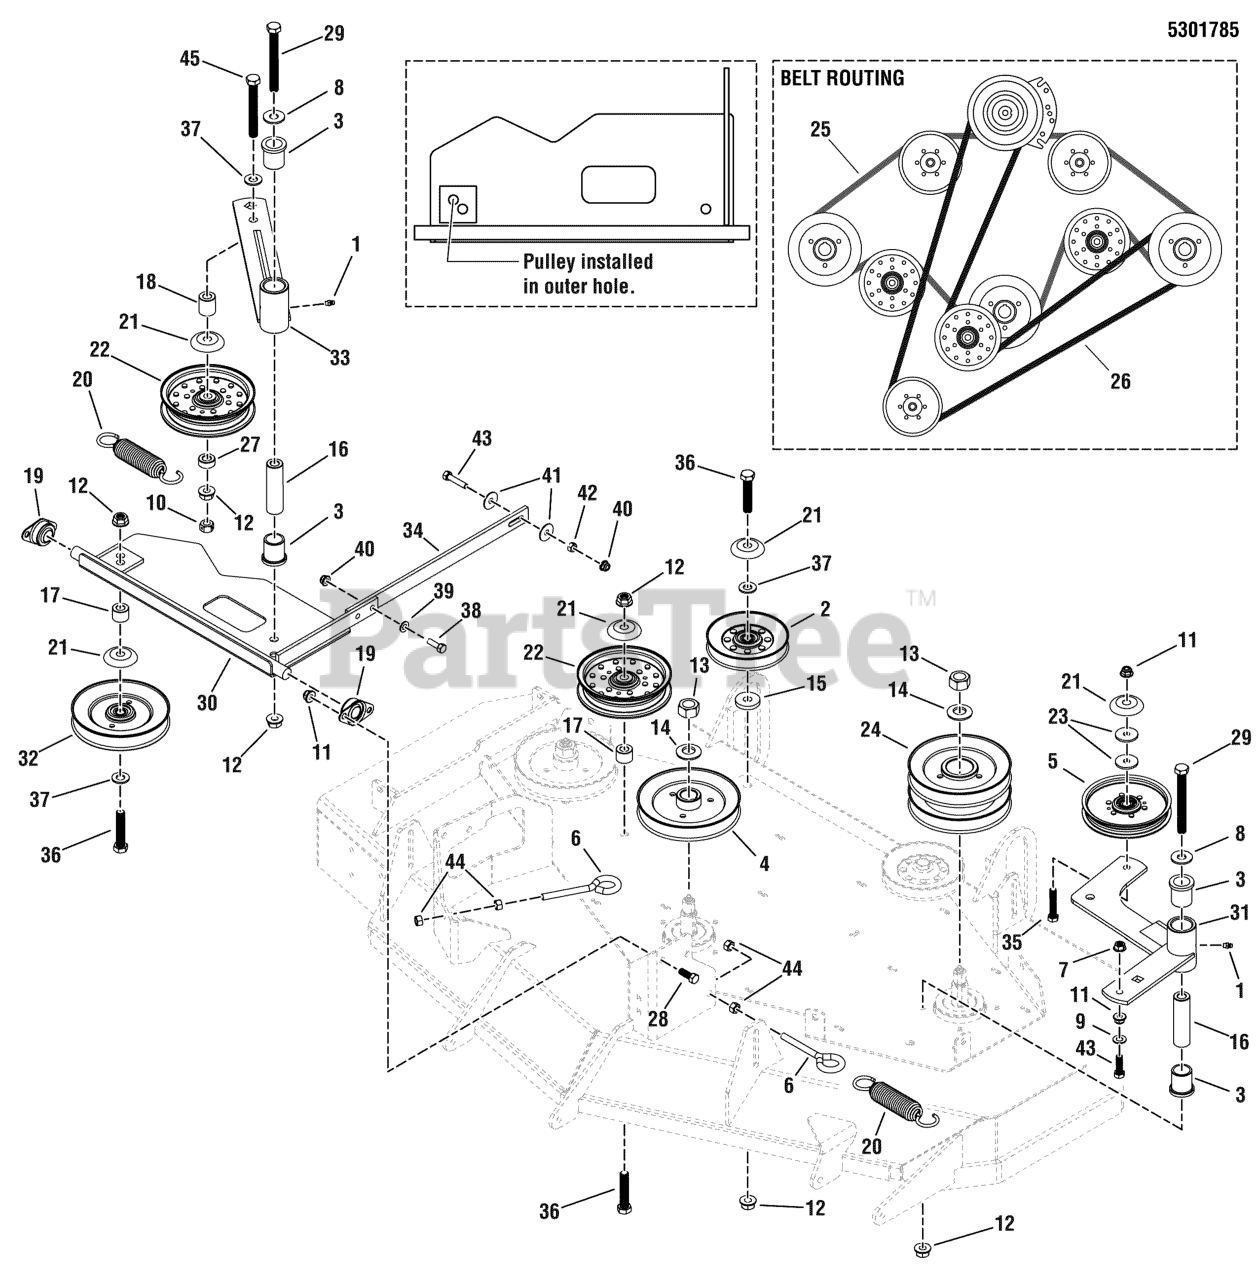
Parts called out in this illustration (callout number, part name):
1	GREASE FITTING, 1/4-28 STRAIGHT
2	PULLEY-IDLER-V, 4.85OB, .506ID, .94W,STL
3	BUSHING, FLANGE
4	PULLEY, 5.926 OVER BALL
5	PULLEY-IDLER, 5.00OD, .385ID, .75W, STL
6	EYE BOLT, 3/8-16 X 5, 2.88THRD, 1EYE, CZ
7	NUT, 3/8-16 HEX SERRATED FLANGE
8	WASHER, 1/2 USS
9	WASHER, 3/8 SAE
10	NUT, 1/2-13 HEX SIDE LOCK
11	NUT, 3/8-16 HEX NYLOCK FLANGE
12	NUT, Hex Flange, Nylock, 1/2-13
13	NUT, 3/4-16 HEX
14	WASHER, 3/4 BELLEVILLE
15	WASHER, .53 X 1.50 X .25
16	SPACER, .52 X 1.00 X 3.50
17	SPACER, .52 X 1.00 X .75
18	SPACER, .52 X 1.00 X 1.15
19	BEARING, BRONZE FLANGE, 3/4"
20	SPRING, EXTENSION, SWIVEL, SHORT HOOK
21	SHIELD, PULLEY BEARING
22	PULLEY, IDLER, 5" OD, 1"FACE, 5.75 FL
23	WASHER, .390 X 1.38 X .109, YZ
24	PULLEY, DOUBLE, 5.926 OVER BALL
25	BELT, B-SECTION, 105 EL, WRAP, ARAMID
26	BELT, B-SECTION, 112 EL, WRAP, ARAMID
27	SPACER, .52 X 1.00 X .44
28	BOLT, 3/8-16 X 1" GD5 CZ
29	BOLT, 1/2-13 X 4-1/2 GD5
30	WELD, IDLER MOUNT PLATE - RED
31	WELD, IDLER, EVOLUTION 48 - RED
32	PULLEY, 6" DEEP GROOVE, COMPENSATOR
33	WELD, IDLER ARM, EVO 36 DECK
34	BAR, 1/4 X 1.00 X 15.50
35	BOLT, 3/8-16 X 2, GD5, CZ
36	BOLT, 1/2-13 X 2-1/2" GD5 CZ
37	WASHER, 1/2 SAE
38	BOLT, 5/16-18 X 1 GD5 YZ
39	WASHER, 5/16" SAE
40	NUT, 5/16-18 HEX NYLOCK FLANGE
41	WASHER, 5/16 FENDER
42	NUT, 5/16-18 HEX SERRATED FLANGE (LARGE)
43	BOLT, 5/16-18 X 1-1/2 GD5 YZ
44	NUT, 3/8-16 HEX
45	BOLT, 1/2-13 X 4" GD5 CZ
